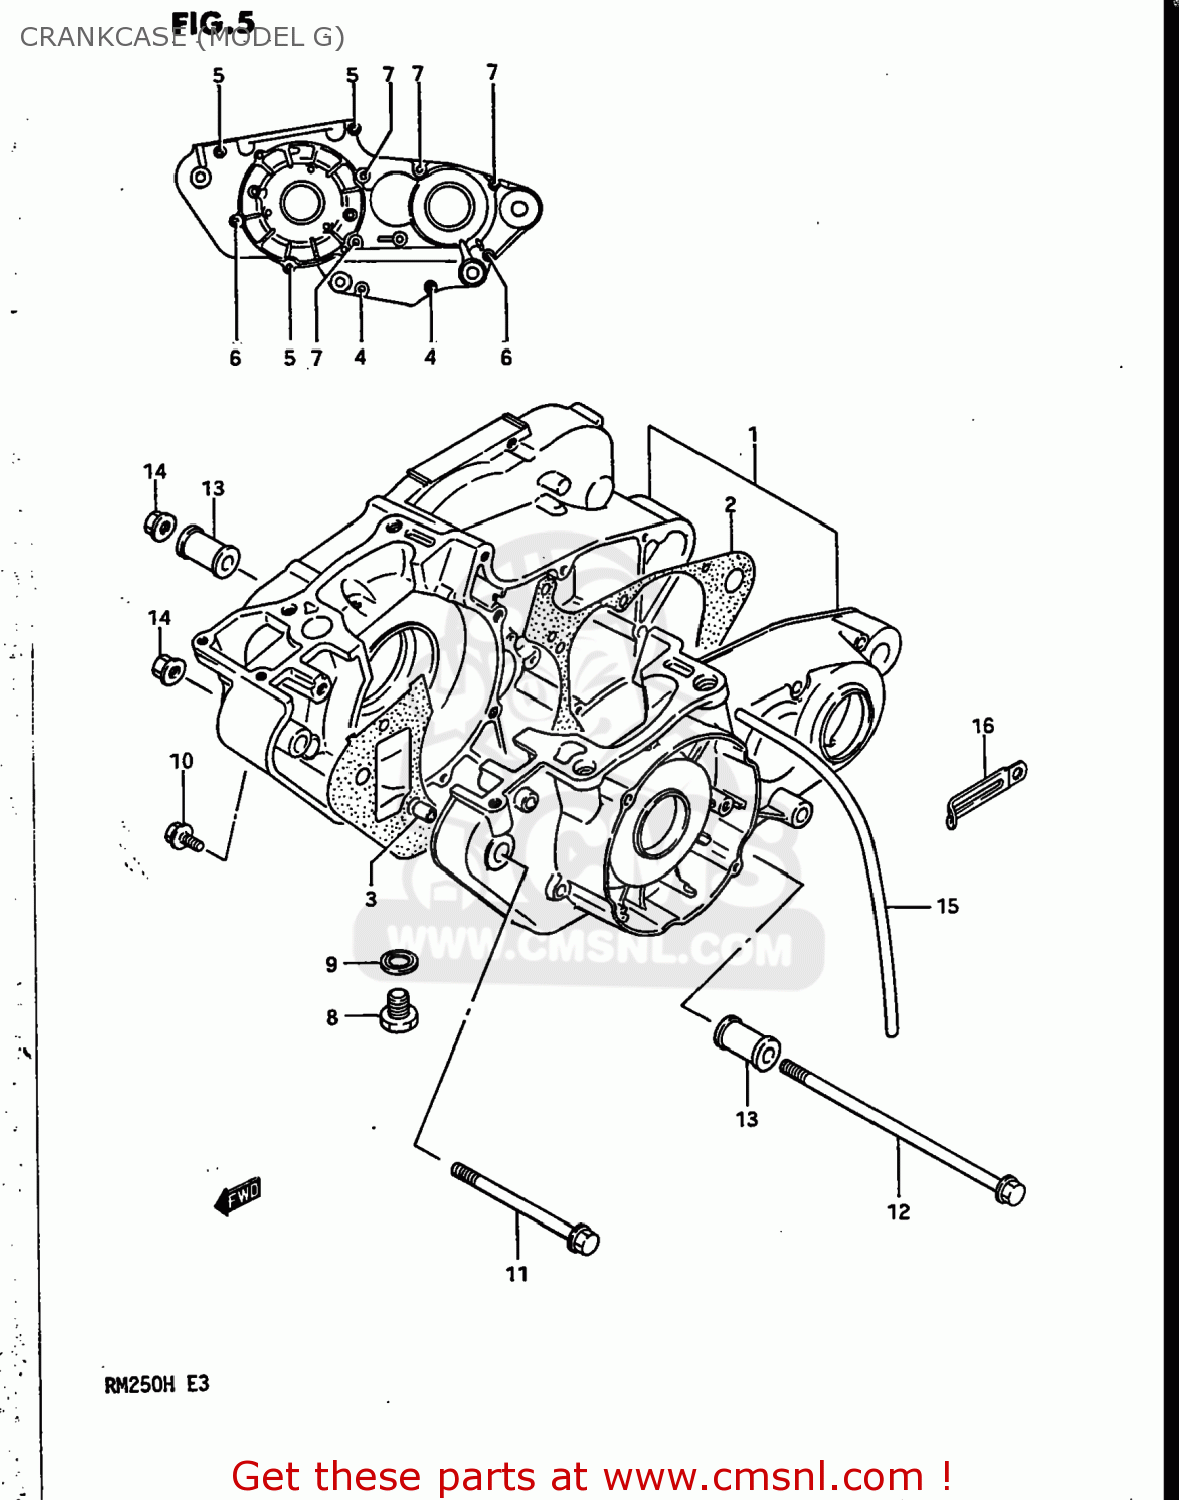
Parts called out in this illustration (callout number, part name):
1	CRANKCASE SET
2	GASKET,CRANKCASE (MCA)
3	PIN
4	SCREW (6X35)
5	SCREW (6X45)
6	SCREW
7	SCREW 6X60
8	PLUG
9	GASKET(14X19.2X2) (NAS)
10	SCREW (6X10)
11	BOLT(8X100)
12	BOLT
13	SPACER,ENGINE MOUNT(L:32)
14	NUT
15	HOSE
16	CLAMP
